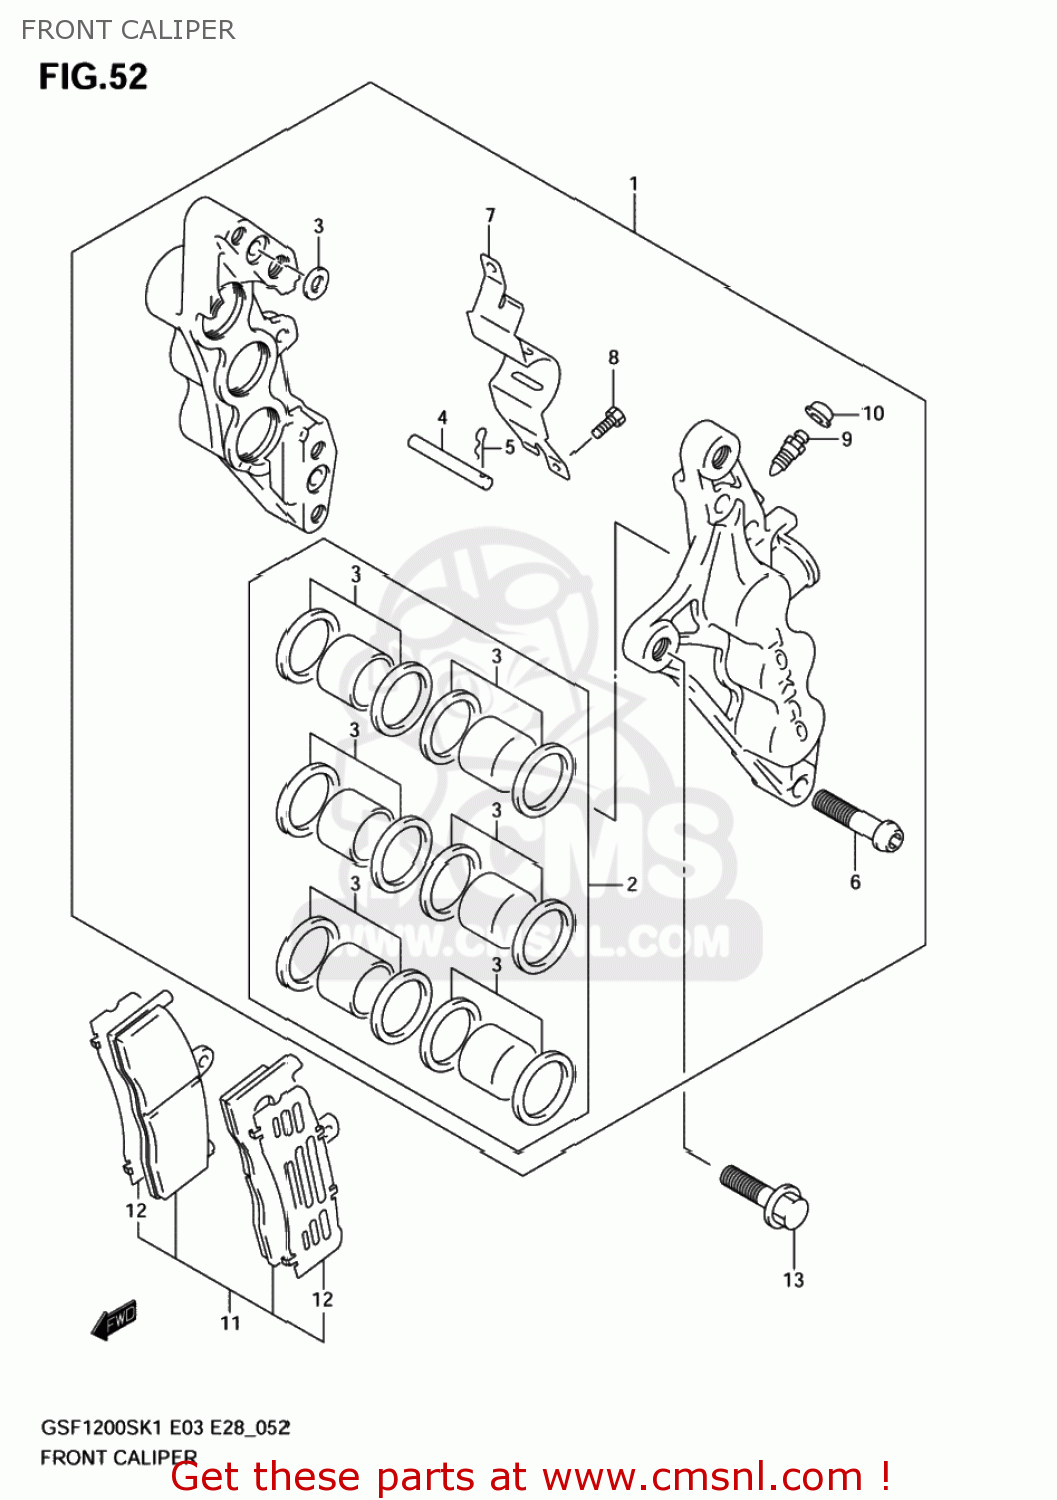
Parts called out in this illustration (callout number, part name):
1	CALIPER ASSY,FR,R
2	PISTON SET
3	SEAL SET,PISTON
4	PIN,PAD
5	CLIP,PAD PIN
6	BOLT
7	COVER,CALIPER
8	SCREW
9	BLEEDER
10	CAP,BLEEDER PLUG
11	PAD & SHIM SET (NAS)
12	SHIM,PAD
13	BOLT
